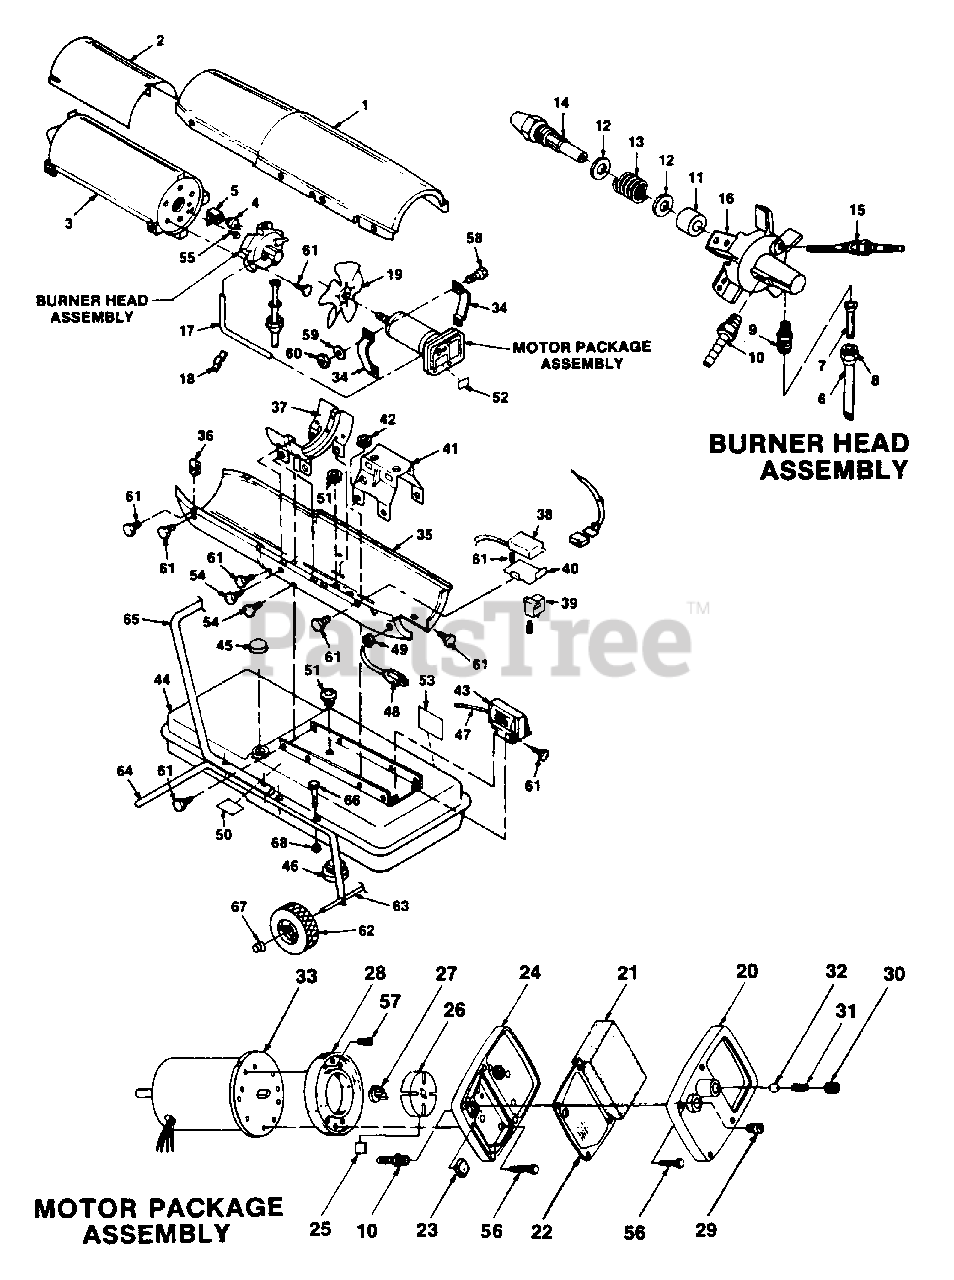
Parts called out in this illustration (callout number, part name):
1	UPPER SHELL
2	DEFLECTOR- Heat
3	CHAMBER- Combustion
4	PHOTOCELL ASSEMBLY
5	PHOTOCELL BRACKET
6	FUEL LINE
7	FILTER- Screen fuel
8	NUT- Flare
9	CONNECTOR- Male
10	FITTING- Barb.
11	SLEEVE- Nozzle
12	WASHER- Nozzle
13	SPRING- Nozzle
14	NOZZLE- 1.1 GPH
15	SPARK PLUG
16	BODY- Burner head
17	AIRLINE TUBING
18	CLIP- Airline
19	FAN
20	COVER- End filter
21	FILTER- Intake
22	FILTER- Output
23	FILTER- Lint
24	COVER- End pump
26	ROTOR- Pump
27	INSERT- Rotor
28	PUMP- Body
30	SCREW- Adjusting
31	SPRING- Relief
32	BALL- 1/4 dia.
34	CLAMP- Motor
35	SHELL- Lower
36	NUT- Clip
37	BRACKET- Shell support
38	CONTROL- Safety
39	SOLID STATE RELAY
40	BRACKET- Solid state relay
41	BRACKET- Motor support
44	TANK- Fuel
45	CAP- Fuel (includes gasket)
46	PLUG- Drain
47	IGNITOR CABLE ASSY.
48	POWER CORD ASSY.
49	BUSHING- Strain Relief
50	DECAL- Fuel
51	BUSHING KIT
52	DECAL- Reset left
53	DECAL- General Info.
64	FRAME SUPPORT WHEEL
65	FRONT HANDLE
66	MOUNTING SCREWS
68	NUT- Hex Lock #10-24
